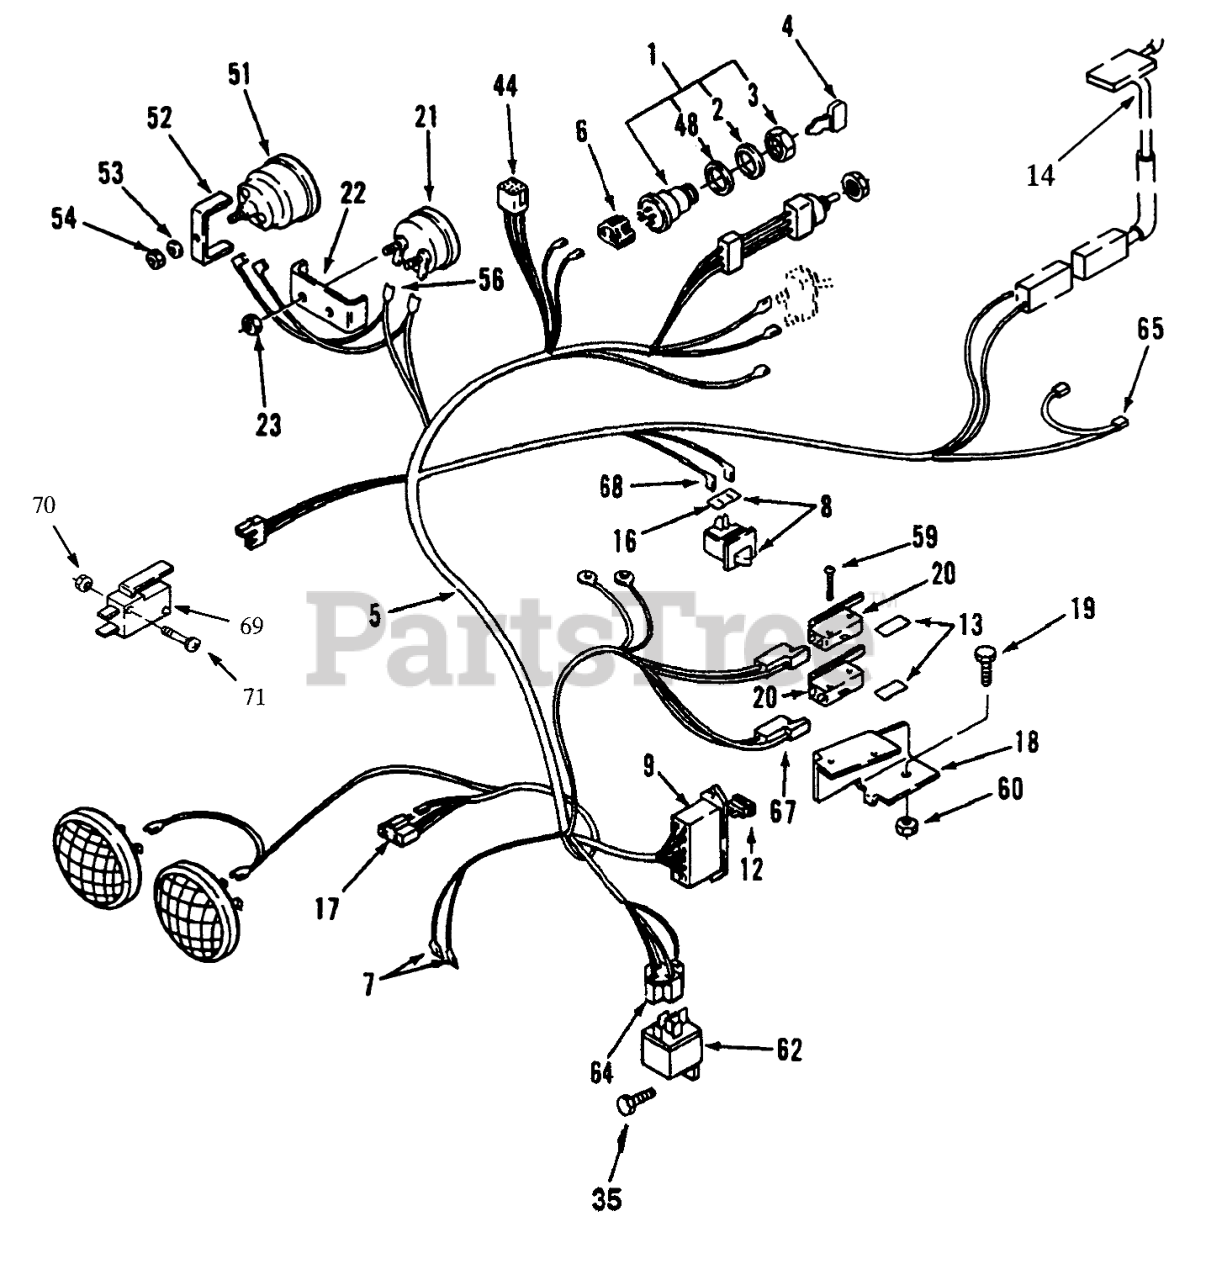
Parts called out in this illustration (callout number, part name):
1	IGNITION SWITCH ASM
2	LOCKWASHER
4	KEY-IGNITION
4	Boot
5	Wiring Harness (Incl.Ref.#6,7,9,17,44,65&68)
6	CONNECTOR BODY ELECT
7	TERMINAL 10
8	Switch-Clutch Interlock, (Incl.Ref.#16)
9	FUSE-HOLDER 4 WAY
12	FUSE-BLADE, 15 AMP
13	BARRIER - SWITCH
14	SWITCH-SEAT
16	SHIELD-DIRT SPST
17	5-CONTACT CONN BODY
18	BRACKET-SWITCH
19	Bolt
20	SWITCH
21	VOLTMETER
22	CLAMP-MOUNTING
23	HEX NUT 10-32 E.S.
48	Washer
51	Meter-Hour (Incl. Ref.# 52-54)
52	BRKT-GAUGE MOUNTING
53	Lockwasher
54	Hex Nut
59	Screw
60	NUT HEX 4-40 ELAST
62	RELAY
64	TERMINAL 10
65	Sur-Plug
68	Terminal
69	SWITCH
70	NUT HEX 4-40 ELAST
71	Screw
